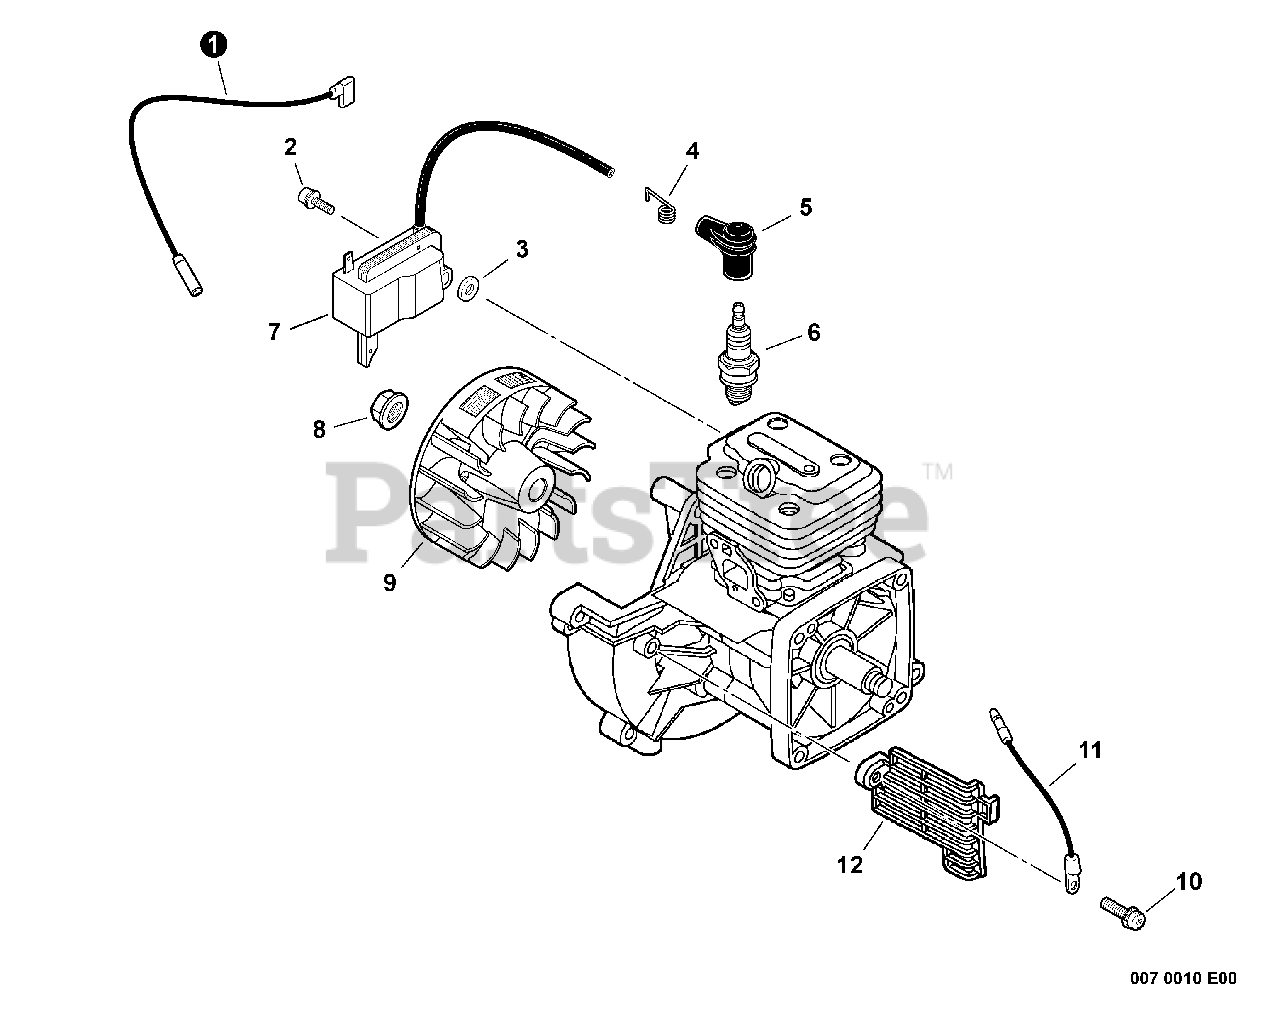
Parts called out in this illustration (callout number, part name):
1	LEAD - IGNITION
2	SCREW - 5X20
4	TERMINAL, SPARK PLUG CAP
5	CAP, SPARK PLUG
6	SPARK PLUG -- BPMR-8Y
7	COIL, IGNITION
8	NUT - 8 -- FLANGE
9	FLYWHEEL
10	SCREW - 5X10
11	LEAD - GROUND
12	GUARD, DEBRIS
